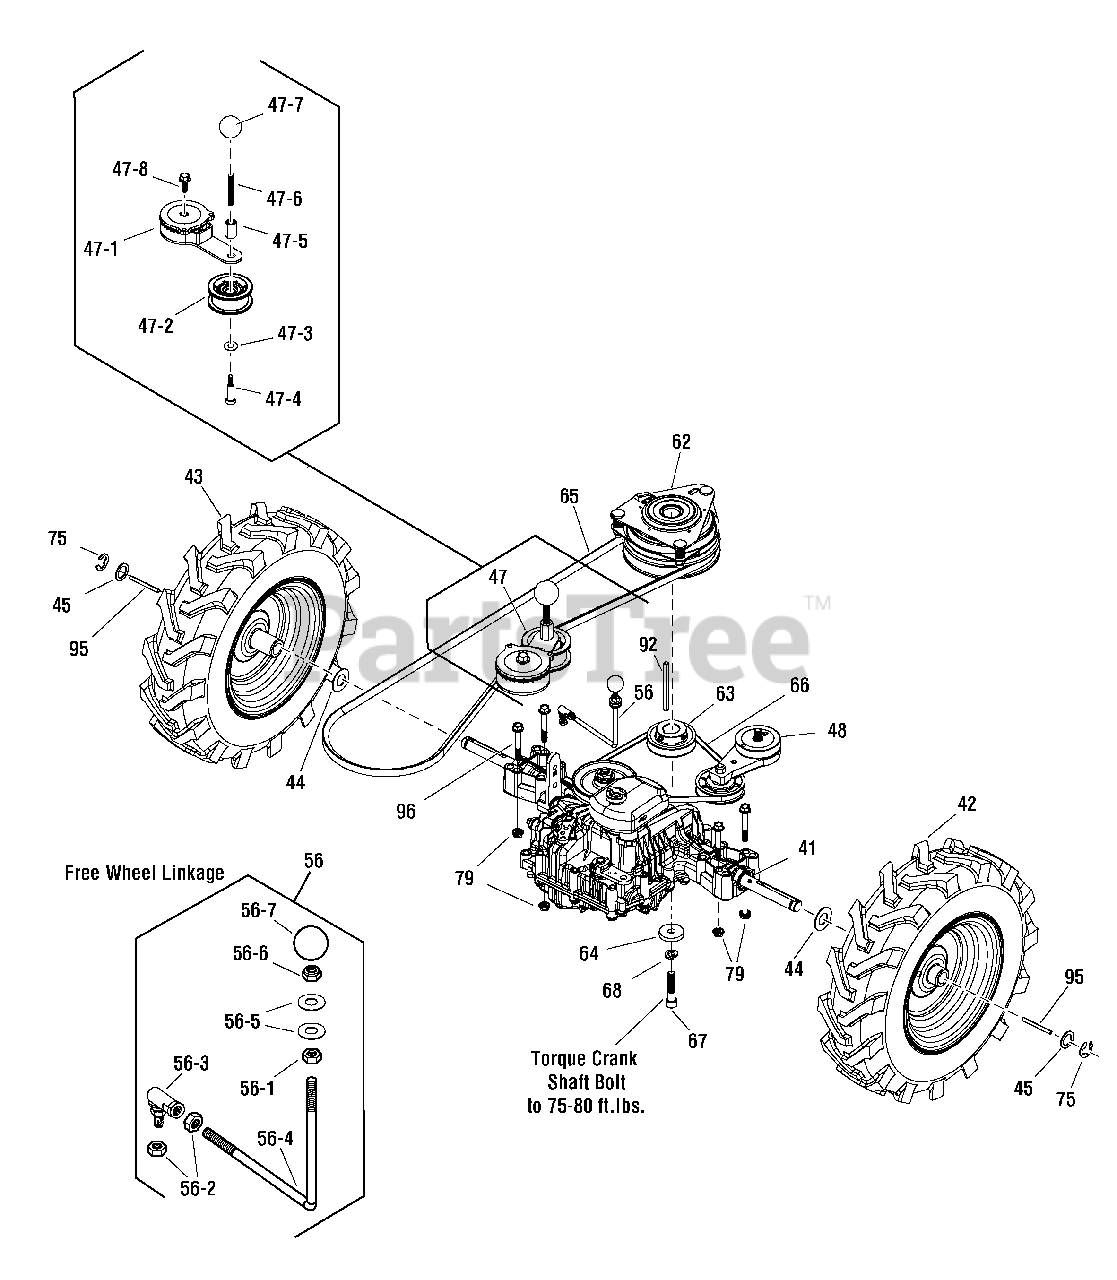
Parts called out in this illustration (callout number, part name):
41	TRANSAXLE TUFF TORQ
42	WHEEL, LEFT
43	WHEEL, RIGHT
44	AXLE WASHER, INNER
45	AXLE WASHER, OUTER
47	BELT TENSIONER, BLADE
47-1	TENSIONER BODY
47-2	TENSIONER PULLEY
47-3	WASHER, TENSIONER PULLEY
47-4	SHOULDER BOLT, 3/8"-16 X 1 / 2" X 1- 1/4"
47-5	COUPLING NUT, 3/8"- 16 X 1- 1/8"
47-6	STUD, BLADE TENSIONER
47-7	BALL KNOB, BELT TENSIONER
47-8	CAPSCREW, FLAT HEAD, 3/8"-16X1"
48	BELT TENSIONER, DRIVE
56	FREEWHEEL LINKAGE
56-1	NUT, 1/4"-20, RH
56-2	NUT, 1/4"-28, RH
56-3	BALL JOINT, 1/4"-28 RH THREAD
56-4	ROD, DRIVE/FREE WHEEL
56-5	WASHER, PVC, 1/4"-20
56-6	LOCKING NUT, NYLON, 1/4" x 20 RH
56-7	BALL KNOB, 1", 1/4"-20 THREAD
62	ELECTRIC CLUCH, OGURA
63	PULLEY, TRANSAXLE, 3-1 /2"
64	RETENTION WASHER
65	BELT, CUTTING BLADE
66	DRIVE BELT
67	CAPSCREW, SOCKET HEAD, 7/16"-20 X 2"
68	LOCK WASHER, 7/16"
75	EXTERNAL RETAINING CLIP, WHEEL
79	HEX NUT, SERRATED, 5/16"-18
92	KEY, 1/4"X 1/ 4" X 3-1/2"
95	AXLE KEY, 3/16" SQ X 2-1 /4"
96	FLANGED HEX BOLT, 5/16-18 X 2- 1/ 4"
